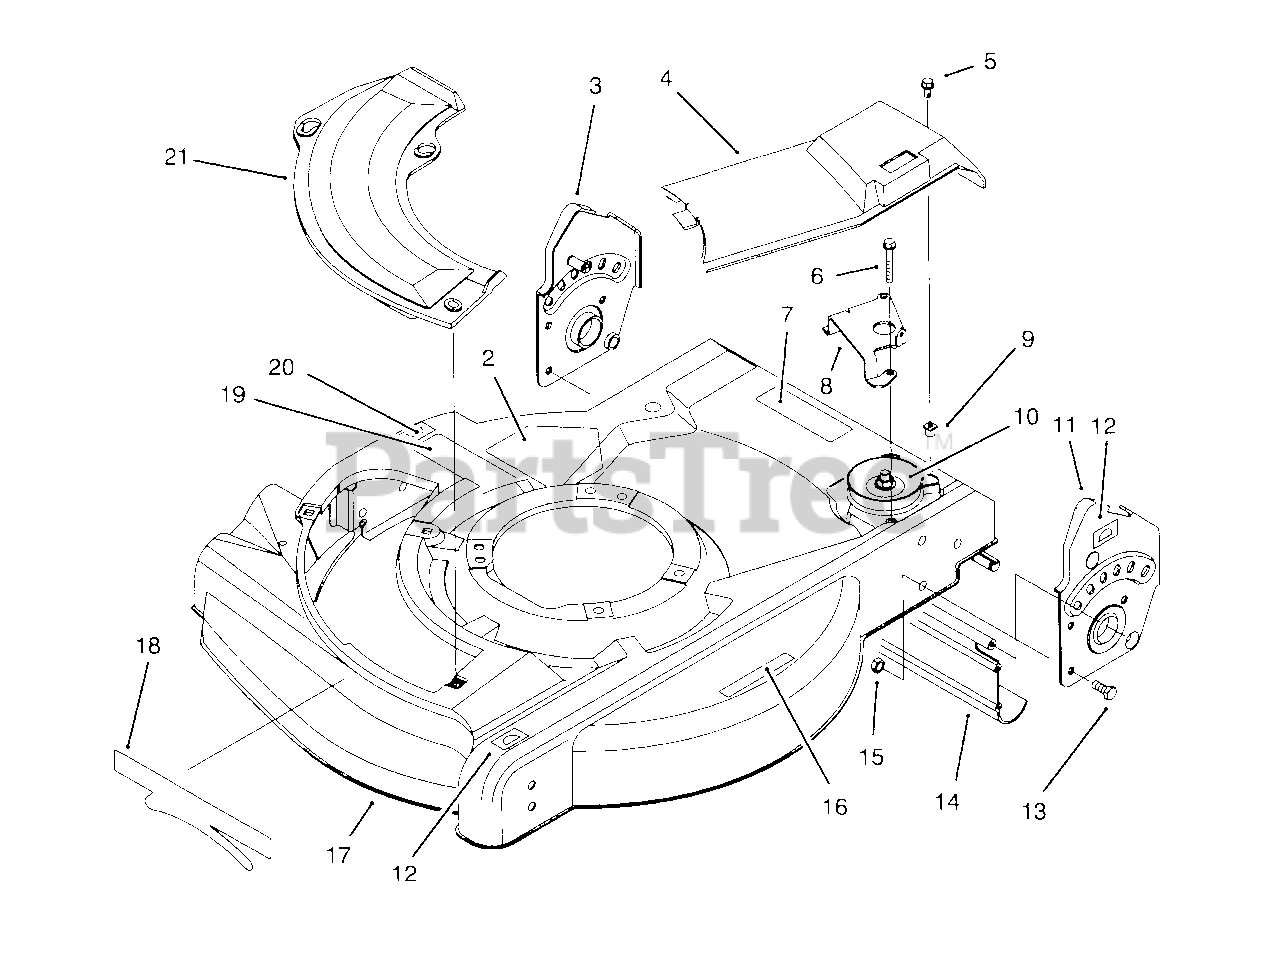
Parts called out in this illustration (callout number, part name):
2	Decal-Danger
3	Bracket-Handle R.H.
4	Cover-Drive
5	Screw-Phillips
6	Hd. Screw-Hex Hd.
7	Cap Decal-Warning
8	Guide-Transmission
9	Grommet
10	Gear Case
11	Assembly Bracket-Handle L.H.
12	Decal-H.O.C.
13	Screw-Hex Hd. Cap
14	Shield-Trailing
15	Nut-Lock
16	Decal-Warning
17	Housing & Baffle Assembly
18	Decal-Deck
19	Decal-Discharge
20	Decal-H.O.C.
21	Plate-Cover
